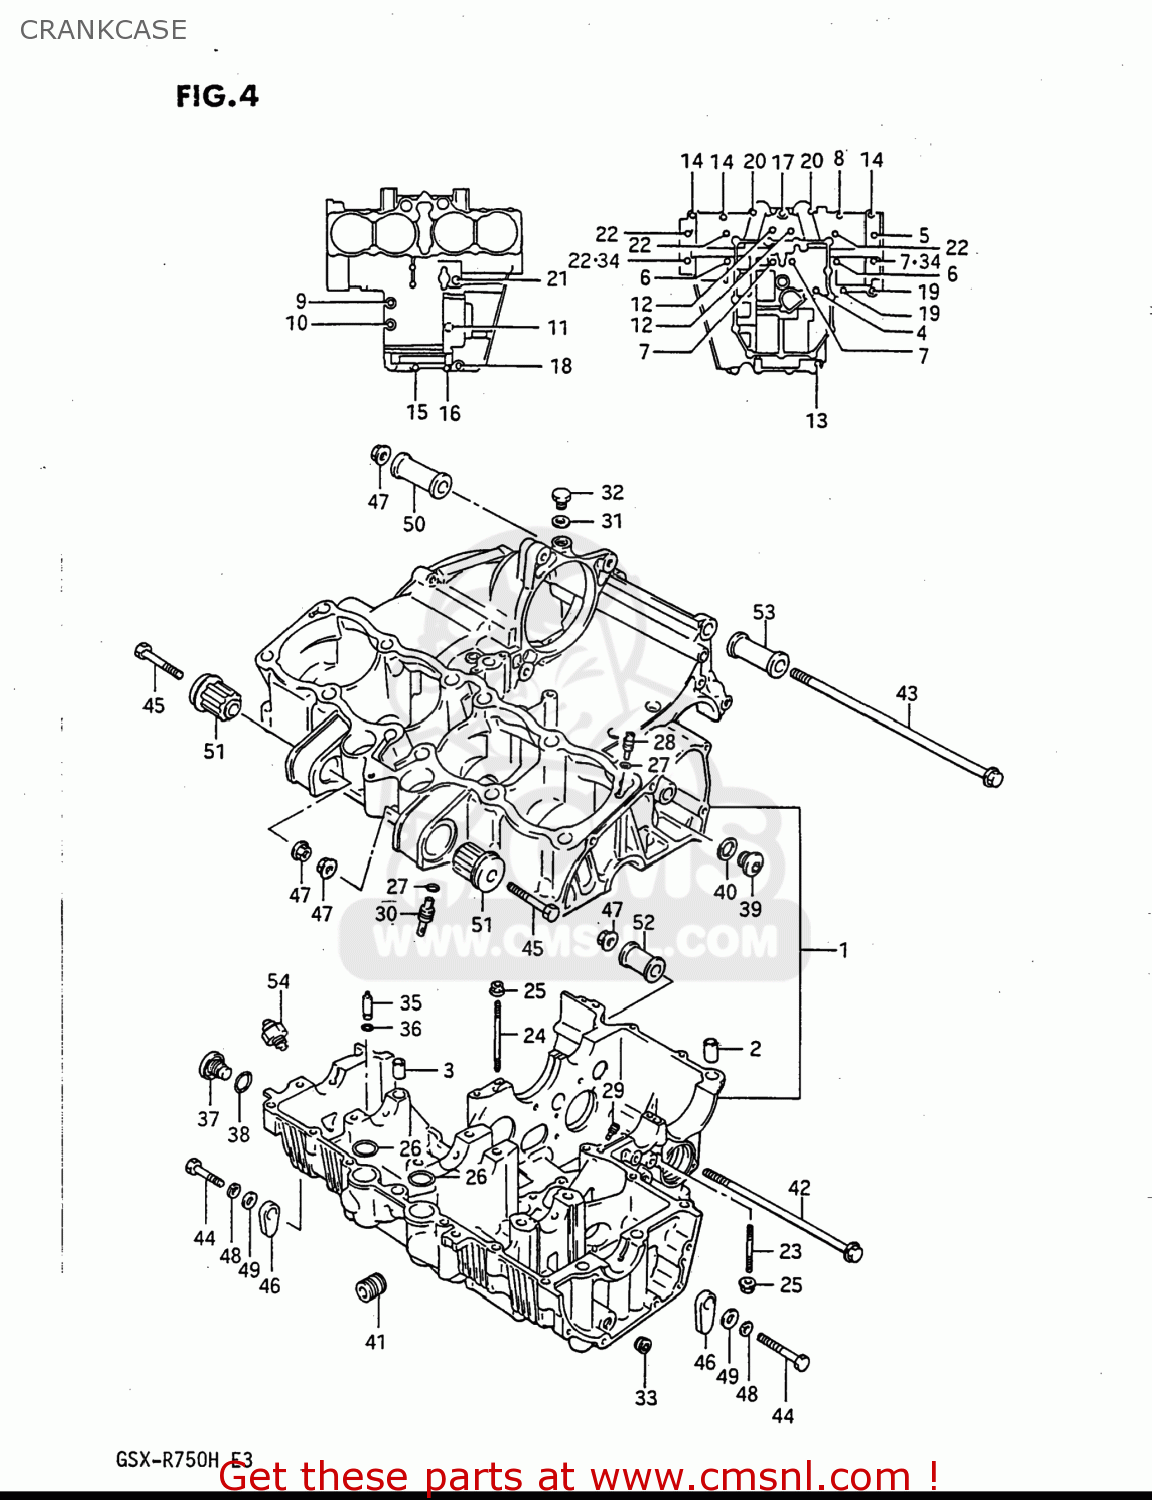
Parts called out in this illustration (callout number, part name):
1	CRANKCASE SET
2	PIN(10.4X13X22)
3	PIN (11X20)(SUS)
4	BOLT(6X105)
5	BOLT(8X105)
6	BOLT(8X125)
7	BOLT(8X115)
8	BOLT 6X35
9	BOLT
10	BOLT
11	BOLT
12	BOLT
13	BOLT 8X60
14	BOLT 6X35
15	BOLT
16	BOLT
17	BOLT 6X50
18	BOLT ,6X60
19	BOLT
20	BOLT
21	BOLT
22	BOLT(8X95)
23	STUD BOLT
24	STUD BOLT
25	NUT
26	O RING(D:2.5,ID:21)
27	O RING(D:1.2,ID:4)
28	JET,AIR
29	JET
30	JET,OIL GALLERY
31	GASKET(12.1X16.2X3.7) (NAS)
32	PLUG(12X9)
33	PLUG(1/4PT,H:7.5)
34	GASKET(8.5X17X2.3) (NAS)
35	VALVE ASSEMBLY,PISTON OIL
36	O RING(D:1.2,ID:4.7)
37	PLUG
38	O RING(D:2.4,ID:16.8)
39	PLUG
40	GASKET(14X19.2X2) (NAS)
41	UNION,OIL STAND
42	BOLT(10X180)
43	BOLT(10X255)
44	BOLT 10X55
45	BOLT 10X55
46	NUT
47	NUT
48	LOCK WASHER
49	WASHER
50	SPACER,ENGINE MOUNT
51	BUSH,ENGINE MOUNTING
52	SPACER,ENGINE MOUNT
53	SPACER
54	SWITCH ASSEMBLY
